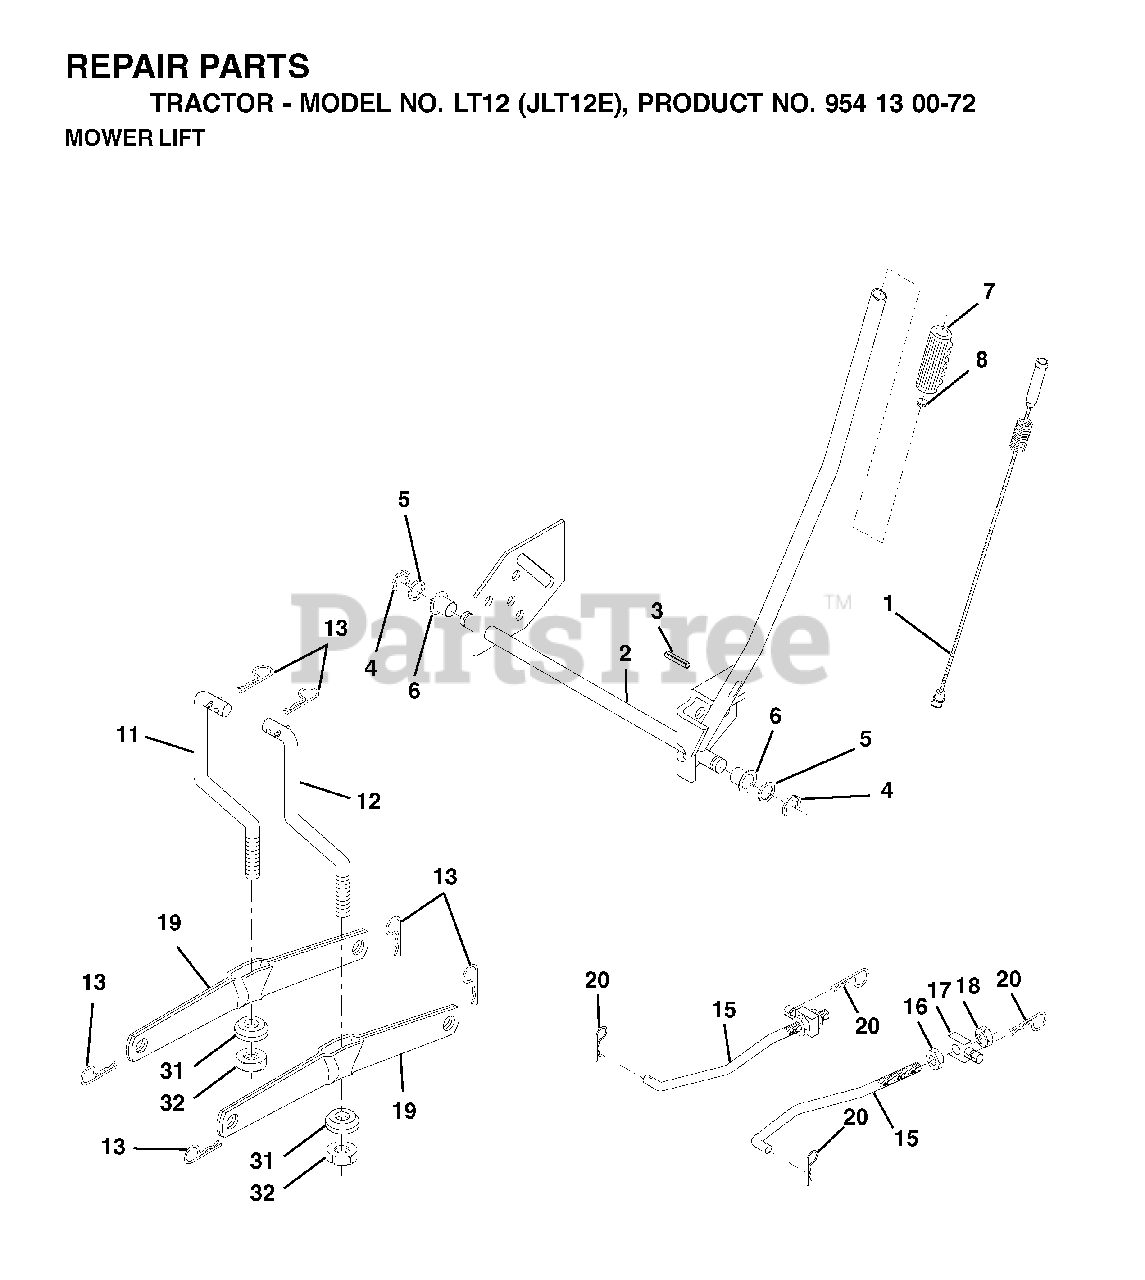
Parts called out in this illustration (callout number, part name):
1	WIRE ASM INNER W/ PLUNGER LT
2	SHAFT ASM R HANDLE
3	PIN GROOVE
4	RETAINING RING LT
6	BEARING.NYLON
7	GRIP
11	LINK LIFT LH
12	LINK LIFT RH
13	RETAINER-SPRNG RB
15	LINK.SUSPENSION.FRONT
16	NUT
18	NUT
19	ARM.REAR.SUSPENSION
20	SPRING RETAINER
31	BEARING.PIVOT.LIFT
32	NUT CROWNLOCK 3/8-24
